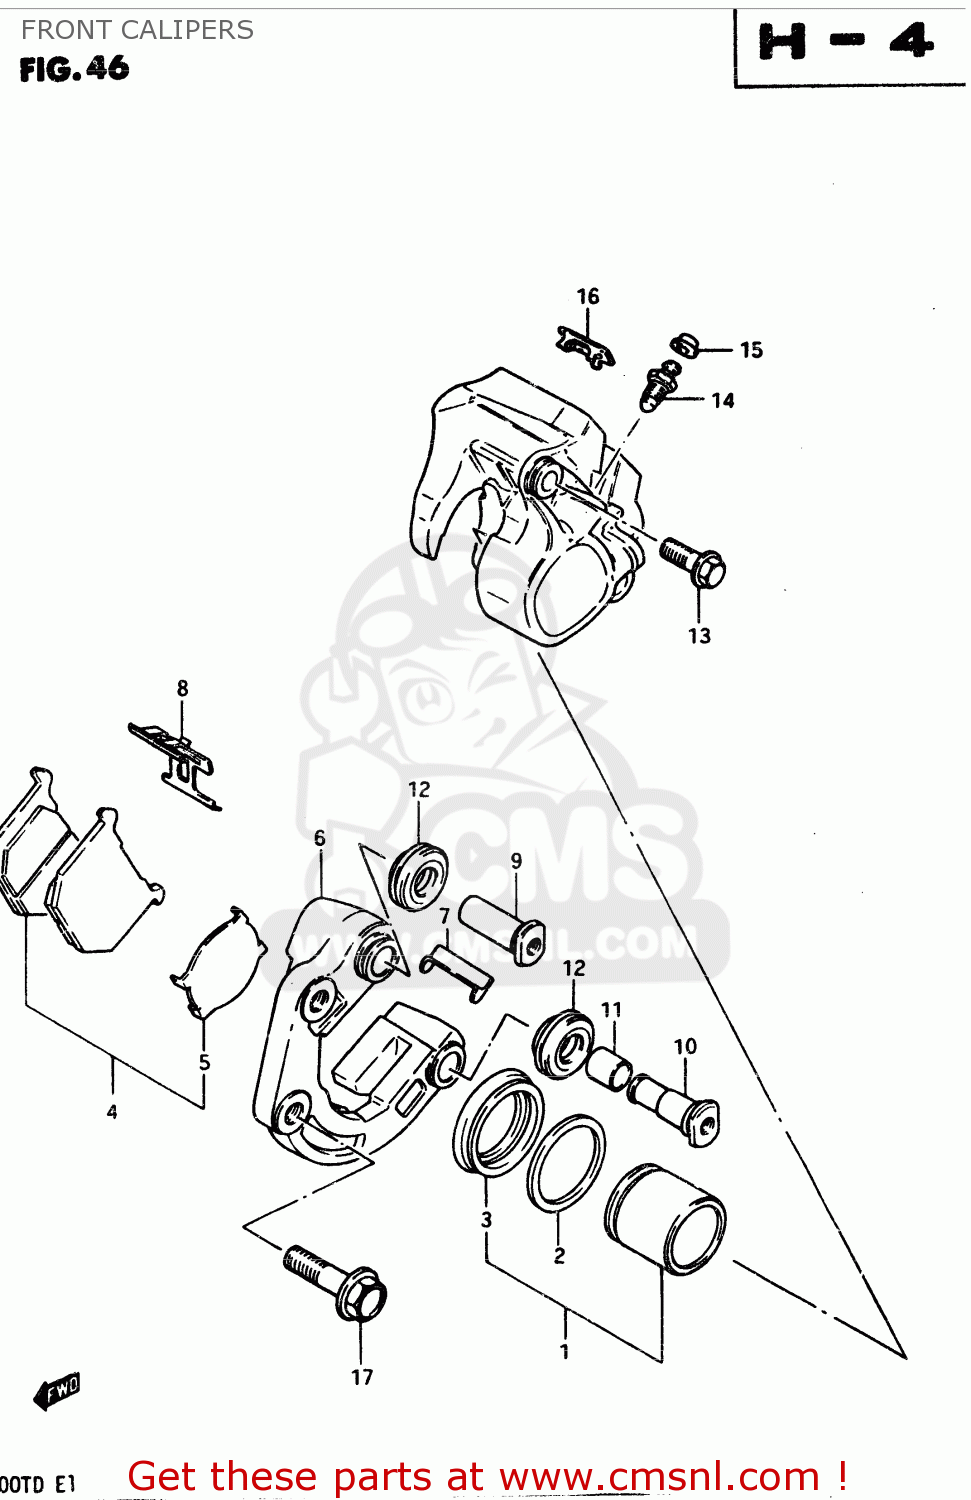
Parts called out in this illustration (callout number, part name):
1	PISTON SET
2	SEAL,FR CALIPE
3	BOOT,PISTON
4	PAD SET,BRAKE (MCA)
5	SHIM,PAD
6	CARRIER,CALIPER,LEFT
7	GUIDE,PAD
8	SPRING,PAD
9	AXLE NO.1
10	AXLE NO.2
11	BUSH,AXLE
12	BOOT,AXLE
13	BOLT
14	BLEEDER
15	CAP,BREATHER
16	COVER
17	BOLT(10X37)
